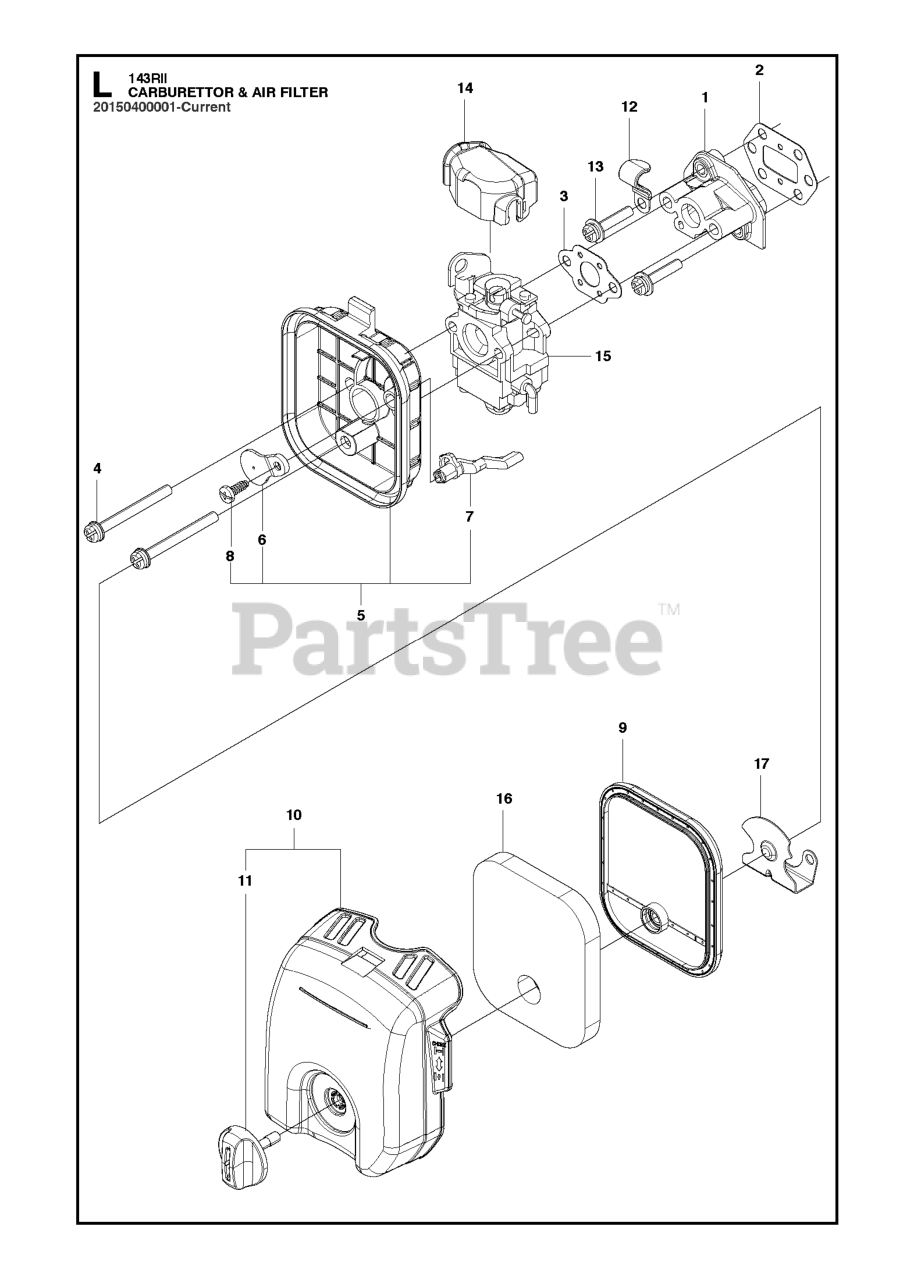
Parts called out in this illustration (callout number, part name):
6	PLATE, CHOKE
7	LEVER.CHOKE
8	SCREW
12	CLAMP
